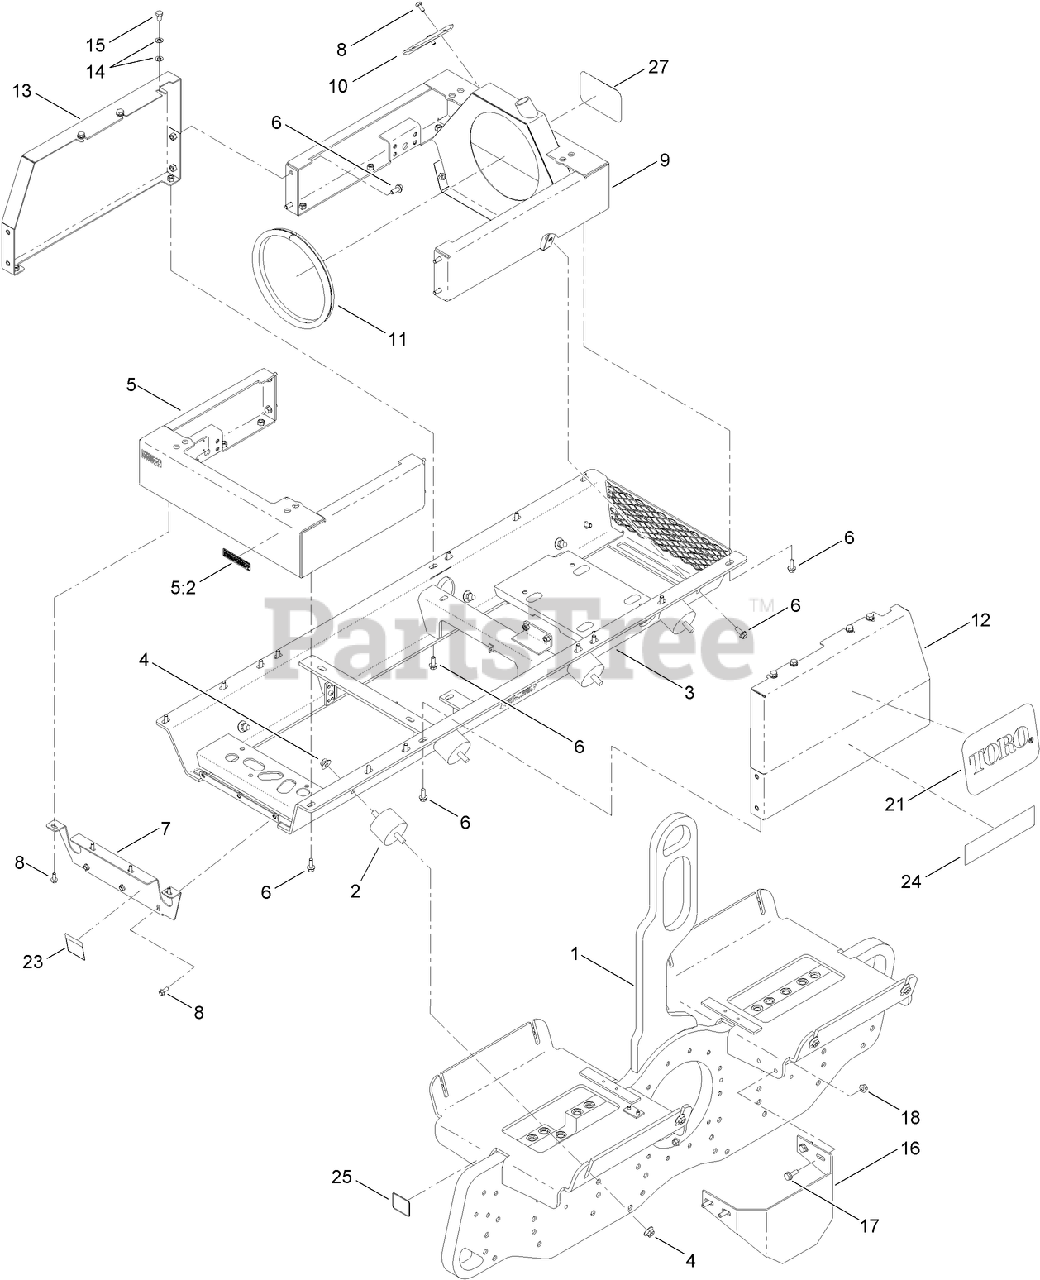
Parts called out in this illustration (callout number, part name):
1	FRAME-LOWER
2	MOUNT-SHOCK, FRAME
3	FRAME-UPPER
4	NUT-HF
5	OPERATOR HOOD RAIL ASM
5:2	DECAL-ARRESTER, SPARK
6	SCREW-HHF
7	COVER-FRAME, LOWER (BACK)
8	SCREW
9	RAIL-HOOD, ENGINE
10	BRACKET-MOUNTING, AIR FILTER
11	SEAL-INLET, AIR
12	COVER-RIGHT
13	COVER-LEFT
14	WASHER-FLAT
15	SCREW-HH
16	GUARD-MOTOR, ECCENTRIC
17	SCREW-HHF
18	NUT-HF
23	DECAL-PARKING BRAKE
25	DECAL-TIE DOWN
27	DECAL
